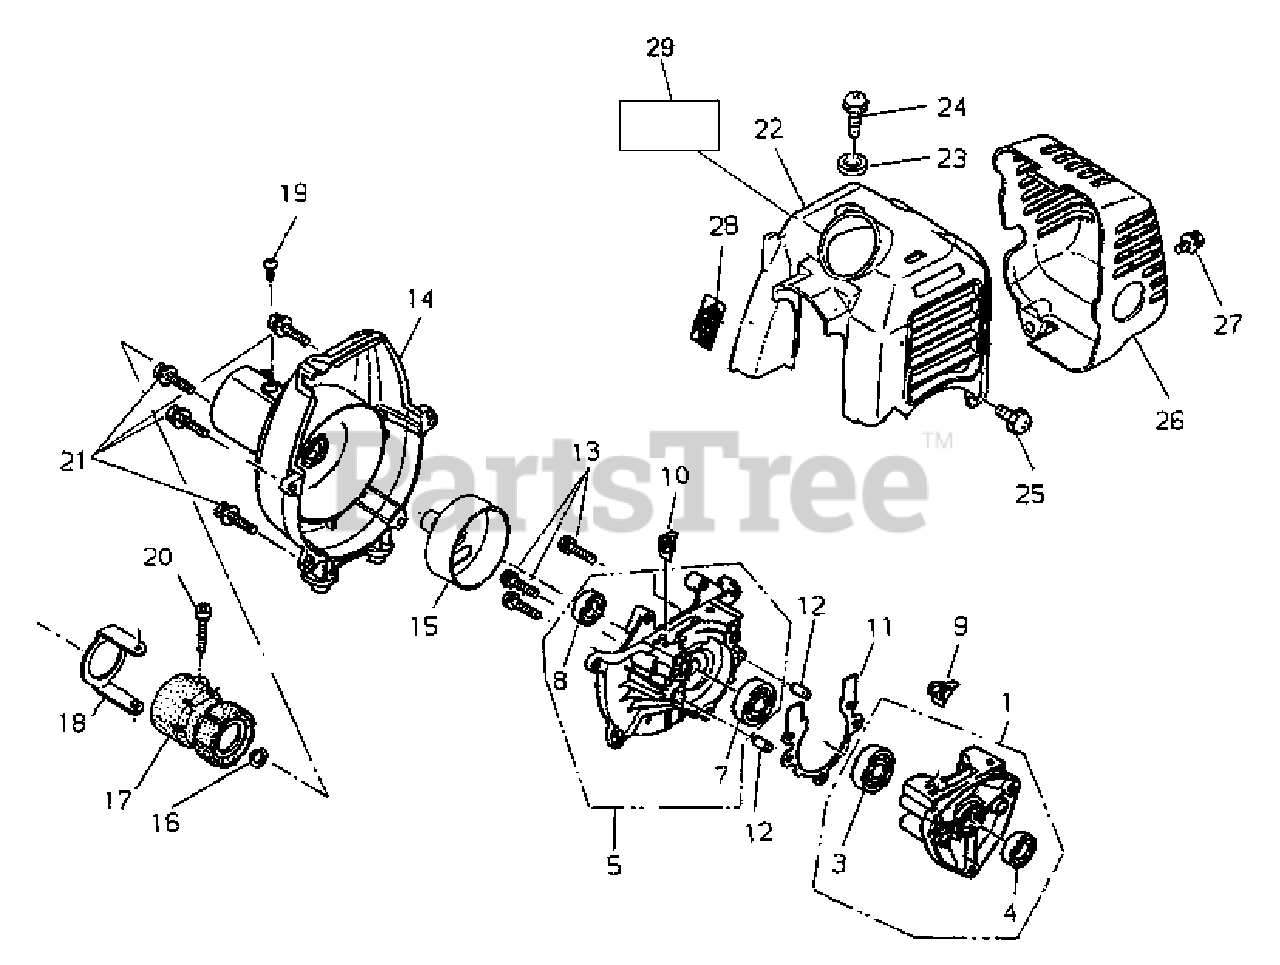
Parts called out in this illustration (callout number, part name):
1	CRANKCASE ASSY - REAR
3	BEARING, BALL
4	SEAL, OIL
5	CRANKCASE ASSY - FRONT
7	BEARING, BALL
8	SEAL, OIL
11	GASKET
12	ROLLER
14	CASE, FAN
15	DRUM, CLUTCH
16	RING, RETAINING
17	CUSHION
18	BRACKET
22	COVER, ENGINE
23	INSULATOR
26	COVER, MUFFLER
28	LABEL - FEATURE
29	LABEL
